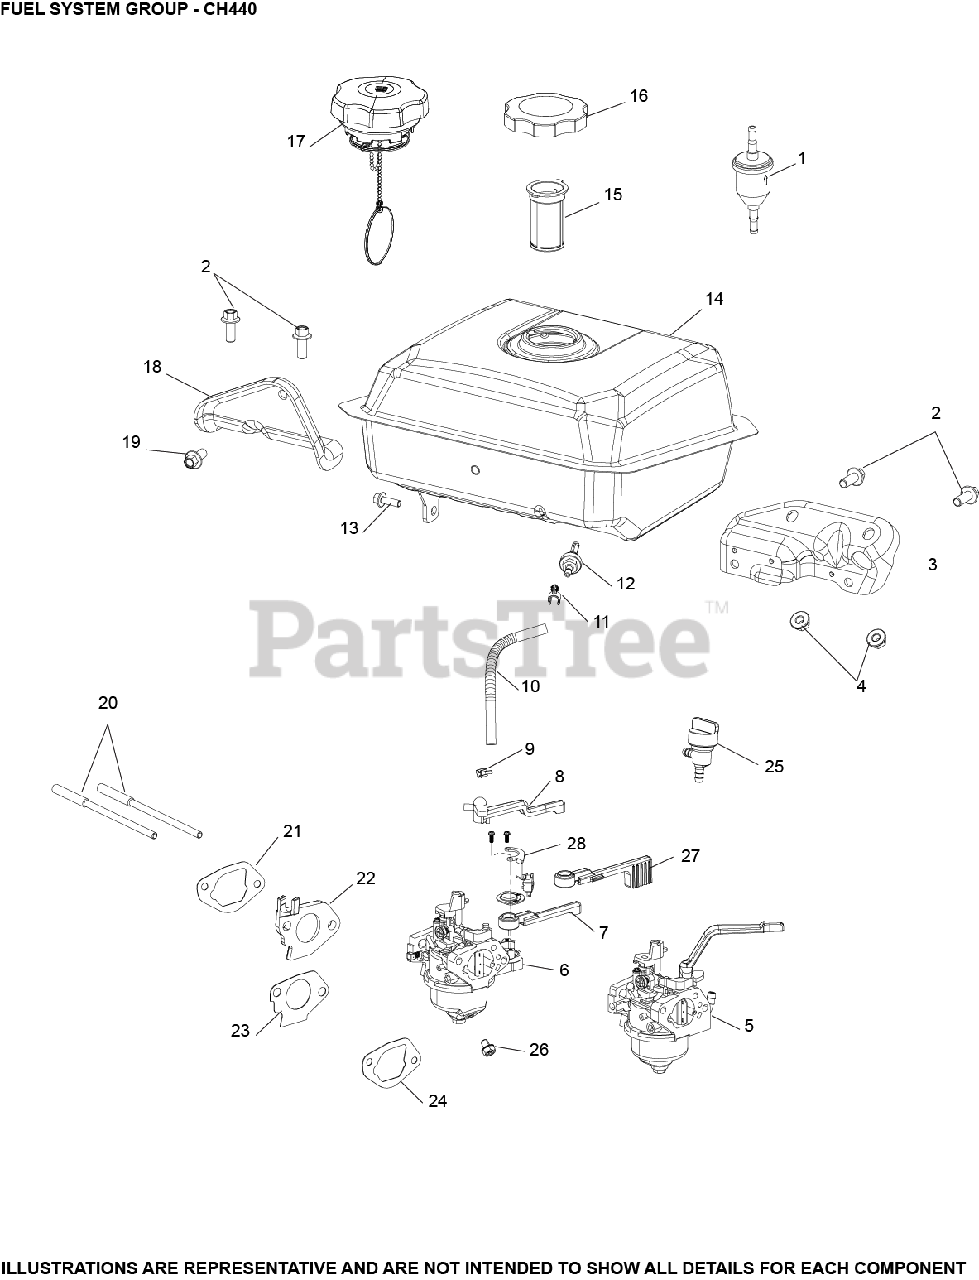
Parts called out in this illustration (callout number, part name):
2	SCREW, M8 X 20
5	KIT, CARBURETOR
9	CLAMP, FUEL LINE
10	FUEL HOSE , LOW PERMEATION
20	STUD, INTAKE
21	KIT, GASKET INTAKE
22	KIT, INSULATOR
23	GASKET, CARB TO INSULATOR
24	GASKET, AIR CLEANER
26	SCREW, BOWL DRAIN (CKY)
